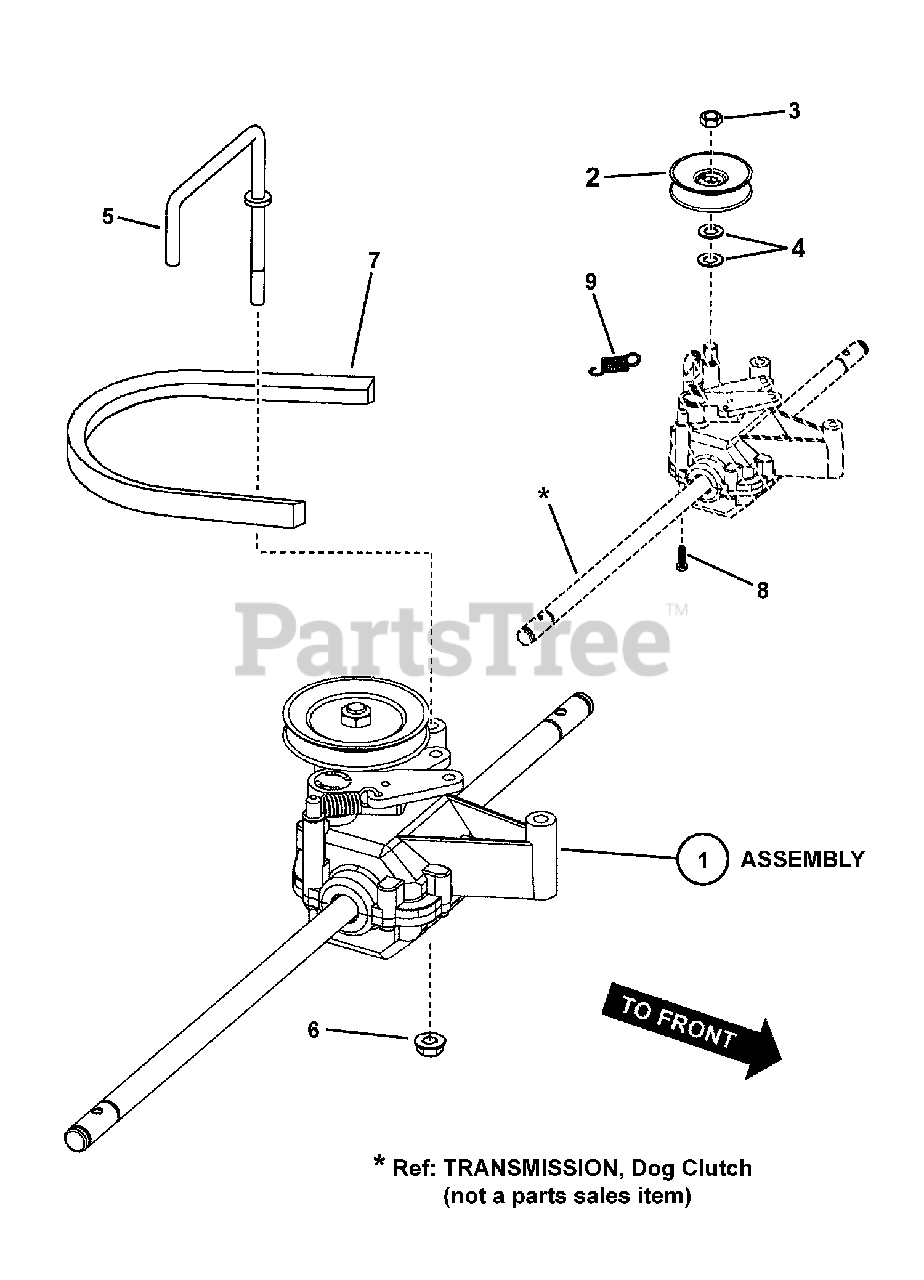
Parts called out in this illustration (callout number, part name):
1	TRANSMISSION, LC Walk, Variable Speed
2	PULLEY, Transmission
3	NUT, 3/8-16 Hex Center Lock Jam
4	WASHER, .390 I.D.
5	BELT GUIDE, Variable Speed
6	NUT, 1/4-20 Hex Top Lock Flange
7	* BELT, 3L, Traction Drive
8	SCREW, 7mm x 1 x .550 AB Point
9	SPRING, Return, Clutch
